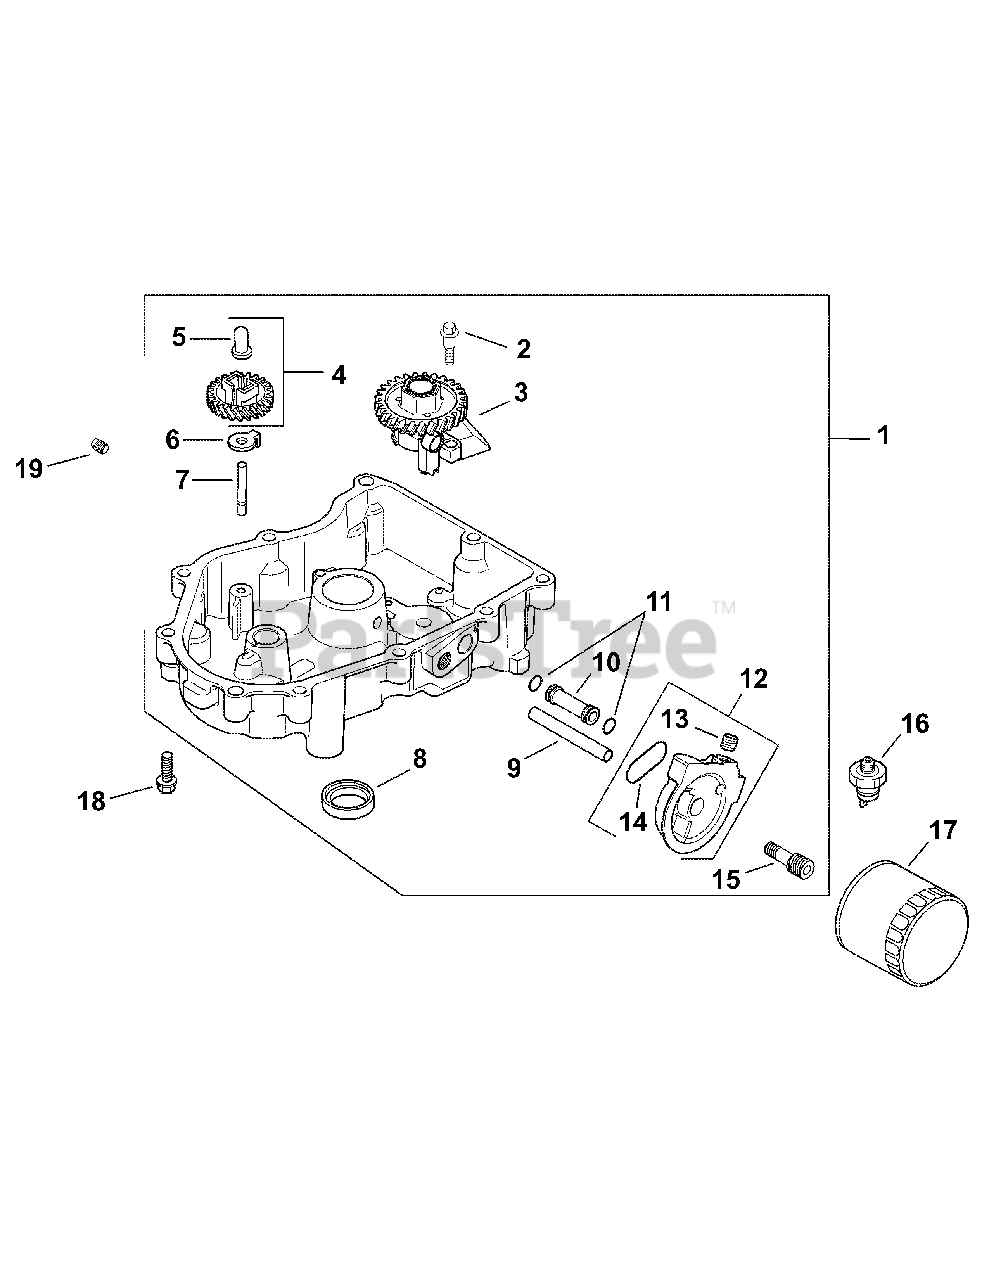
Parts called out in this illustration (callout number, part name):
1	Pan, Oil Assembly (Includes 2-16)
2	Screw, SHD THD FRM M6 x 1.0 x 26.5
3	Pump Assembly, Oil
4	Kit, Governor Gear w/ Pin (Includes 5)
5	Pin, Governor Regulating
7	Shaft, Governor Gear
9	Tube, Oil Feed-Filter to Pan
10	Tube, Oil Feed-Pan to Filter
11	O-Ring, Oil Pick-Up
12	Kit, Adaptor Oil Filter (Includes 13, 14)
13	Plug, CTSK 1/8"
14	O-Ring, Oil Filter Adaptor
15	Nipple, Oil Filter
16	Switch, Oil Pressure
17	Filter, Oil
18	Screw, Flg M8 x 1.25 x 45
19	Plug, Sq Hd Pipe 3/8"
